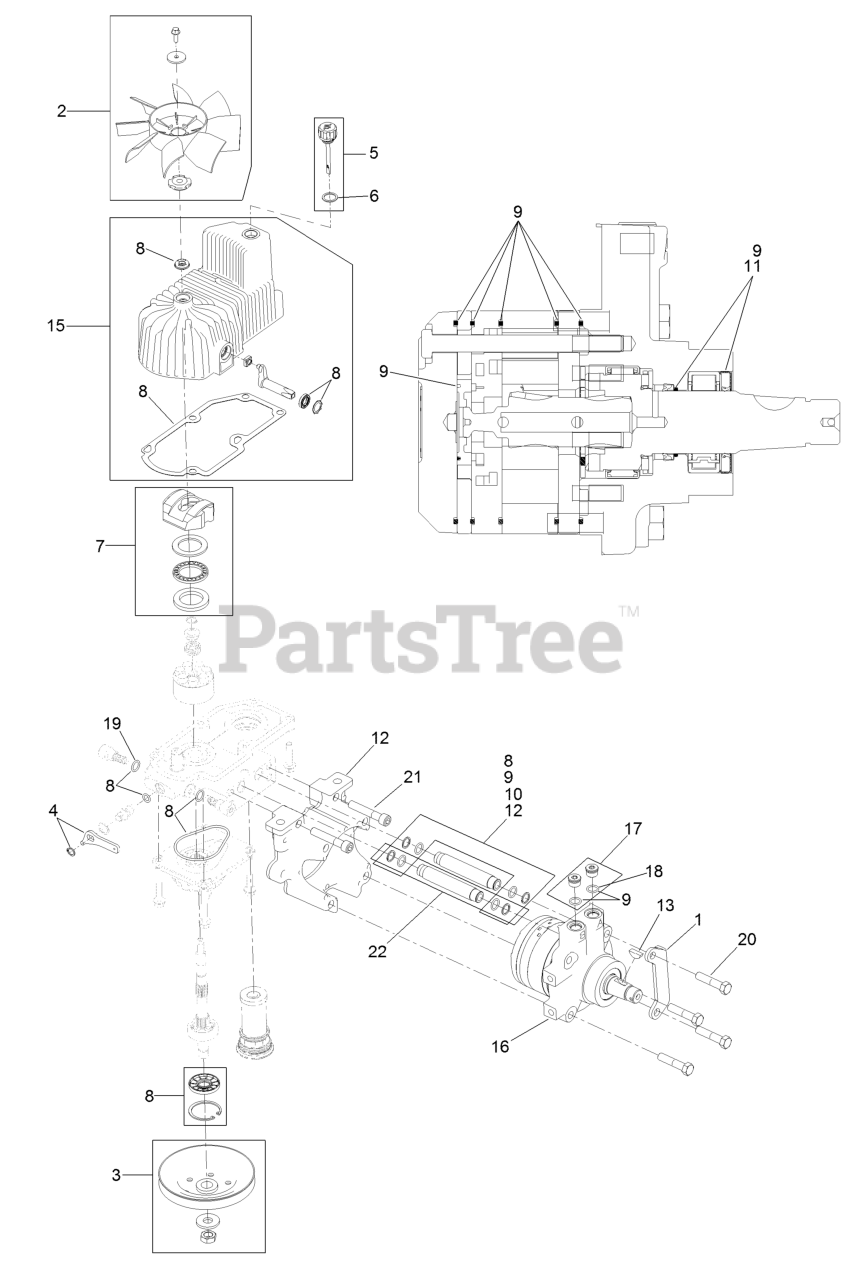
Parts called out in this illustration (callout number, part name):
1	MOUNT-SHOE, HORSE
2	FAN KIT
3	PULLEY KIT
4	HANDLE-BYPASS VALVE, HYDRO
5	DIPSTICK-HYDRO W/GASKET
6	GASKET-DIPSTICK, HYDRO
7	SWASH BLOCK KIT
8	PUMP SEAL KIT
9	MOTOR SEAL KIT
10	TUBE SEAL KIT
11	OUTPUT SHAFT SEAL KIT
12	NOSE CUP-UHT
13	KEY-WOODRUFF
15	HOUSING-HYDRO, RH
16	MOTOR-HYDRAULIC, RH 280CC
17	MAGNETIC PLUGS SERVICE KIT
19	O-RING-CHECK VALVE
20	SCREW HH
21	SCREW-HSH
22	HYDRAULIC TUBE KIT
